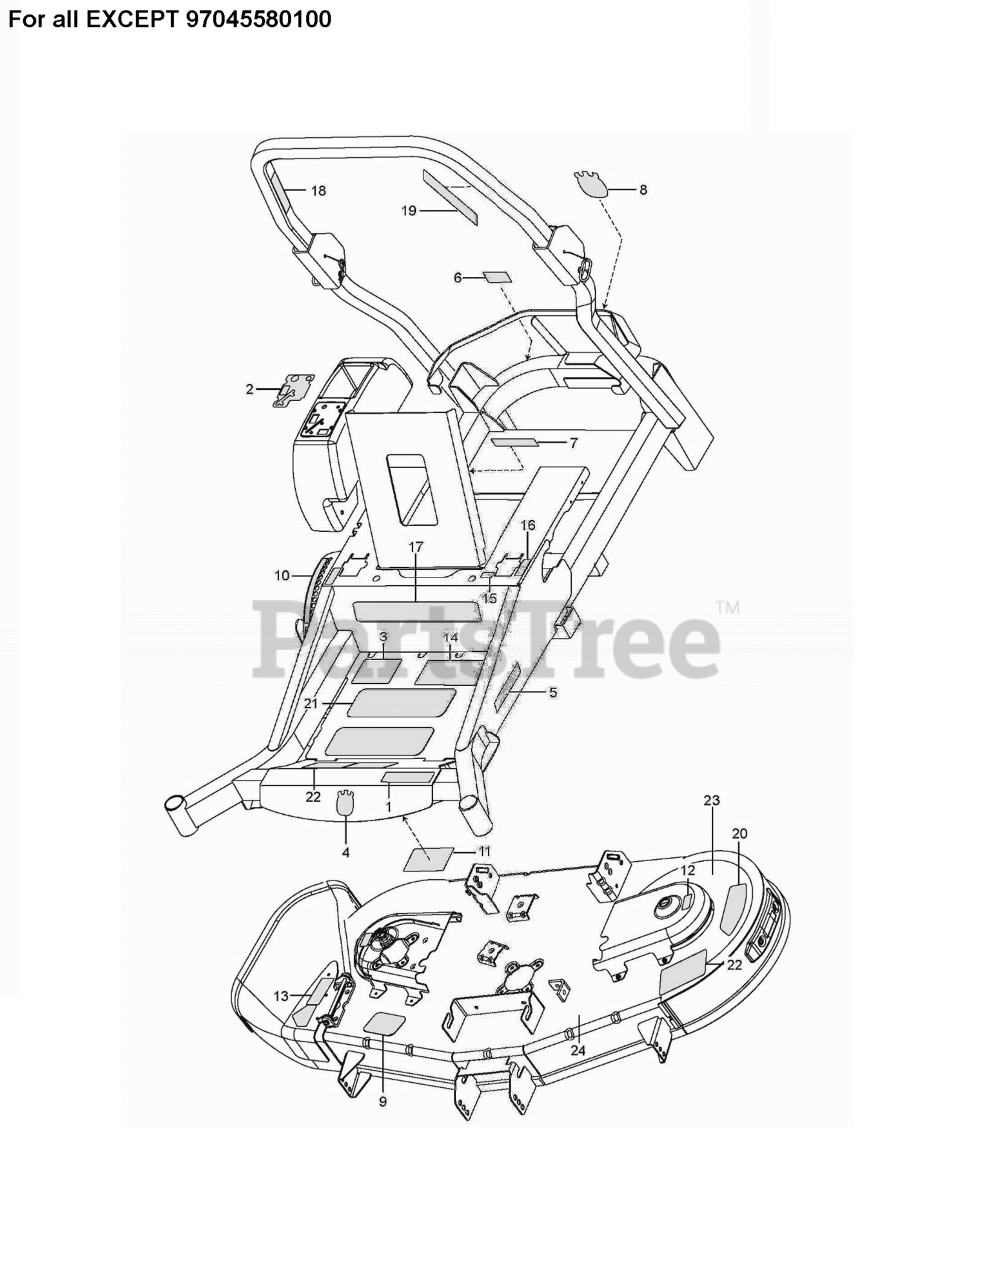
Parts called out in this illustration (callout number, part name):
1	DECAL ZTR MODEL NUMBER DECAL.Z
2	DECAL, CONSOLE HUS
3	DECAL.ZTR.STRTNGINST.REMOTECHK
4	DECAL.AUGER.HUSQ.CROWN.SNOW
5	RP.DECAL.BADGE.170MM.TEXTLOGO
6	DECAL, BELT DRIVE
7	EURO DECAL-BATTERY WARNIN6
8	DECAL, CROWN H, 110MM
9	DECAL BELT ROUTING DECAL DECAL
10	DECAL, HEIGHT ADJUST
11	DECAL, SERVICE
12	DECAL.DECK.CLEARCUT.NOSTEP
13	DECAL.TRACT/ZTR.DECKWARN.HUSQ
14	DECAL ZTR WARNING DECAL DECAL.
15	DECAL.STR.S.T.SYSMBOLONLY.2014
16	DECAL.ZTR.MOTCONTRL.SYMBOL.HUS
17	DECAL ZTR BRAND GRAPHIC DECAL.
18	DECAL, ROPS, WARNING
19	DECAL.ROP.Z400/400X.MZ/MZT/RZ
19	DECAL.ROPS. Z400/400X
19	DECAL ROPS
20	DECAL.54DECK.CLEARCUT.VER2.18
21	ANTI-SKID PAD
23	DECAL DECK DECAL DECAL.DECK.WA
24	DECAL BELT ROUTING DECAL DECAL
